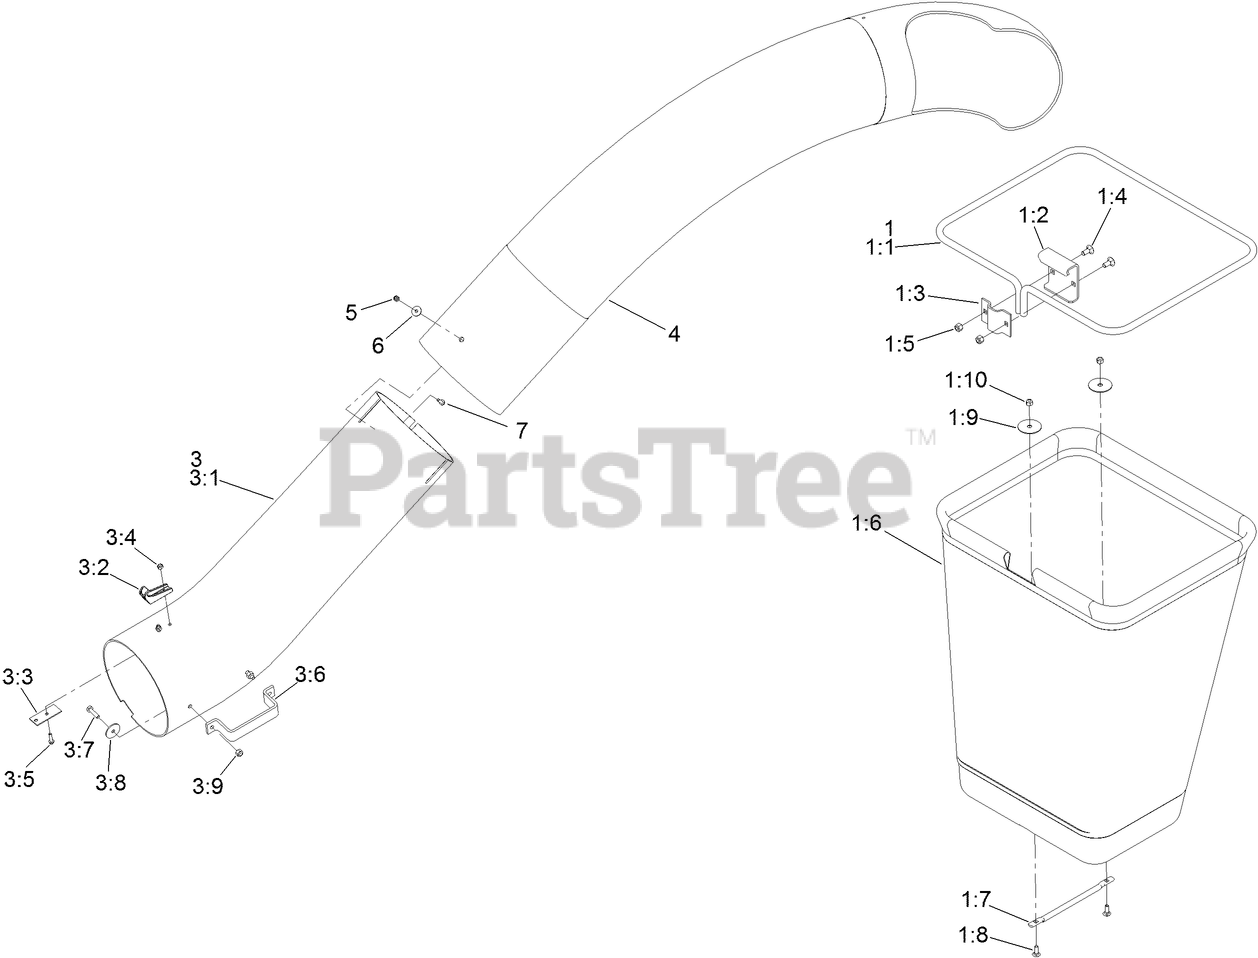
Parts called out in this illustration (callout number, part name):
1	BAG AND FRAME ASM
1:1	FRAME-BAG
1:2	HANGER-BAG
1:4	BOLT-CARR
1:5	NUT-LOCK, NI
1:7	HANDLE-BAG
1:8	BOLT-CARR
1:9	WASHER
1:10	NUT-LOCK, NI
3	LOWER TUBE ASM
3:2	LATCH-CATCH
3:3	PLATE-BACKING
3:4	TUBE-LOWER
3:5	SCREW-HH
3:6	WASHER-FLAT
3:7	NUT-LOCK, NI
3:8	NUT-LOCK, NI
3:9	SCREW-HWH
4	TUBE-UPPER
5	NUT-LOCK, NI
6	WASHER-FLAT
7	SCREW-HWH
